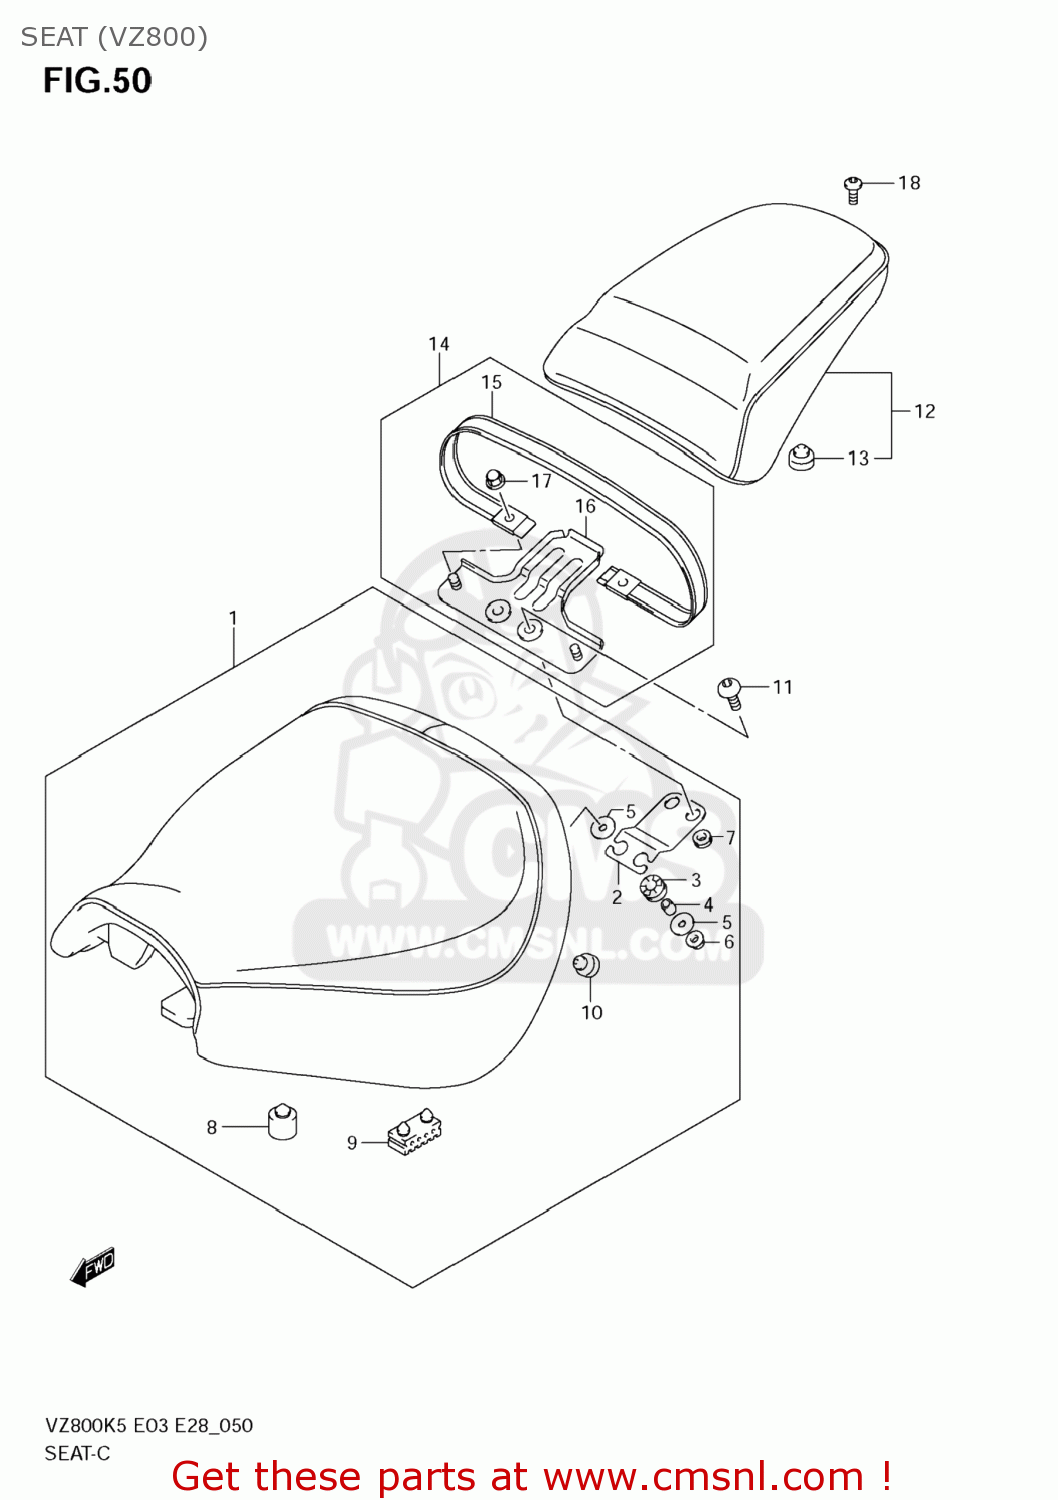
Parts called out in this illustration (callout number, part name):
1	SEAT ASSY
2	PLATE,SEAT FR
3	CUSHION
4	SPACER(6.5X10.5X12)
5	WASHER(6.5X24X1.6)
6	NUT
7	CUSHION
8	CUSHION
9	CUSHION,SEAT(40X20X15)
10	CUSHION(11.5X22X20)
11	BOLT(6X18)
12	SEAT ASSY,PILLION
13	CUSHION(11.5X22X20)
14	BAND ASSY,SEAT
15	BAND
16	BRACKET,SEAT BAND
17	NUT
18	BOLT(8X16)
